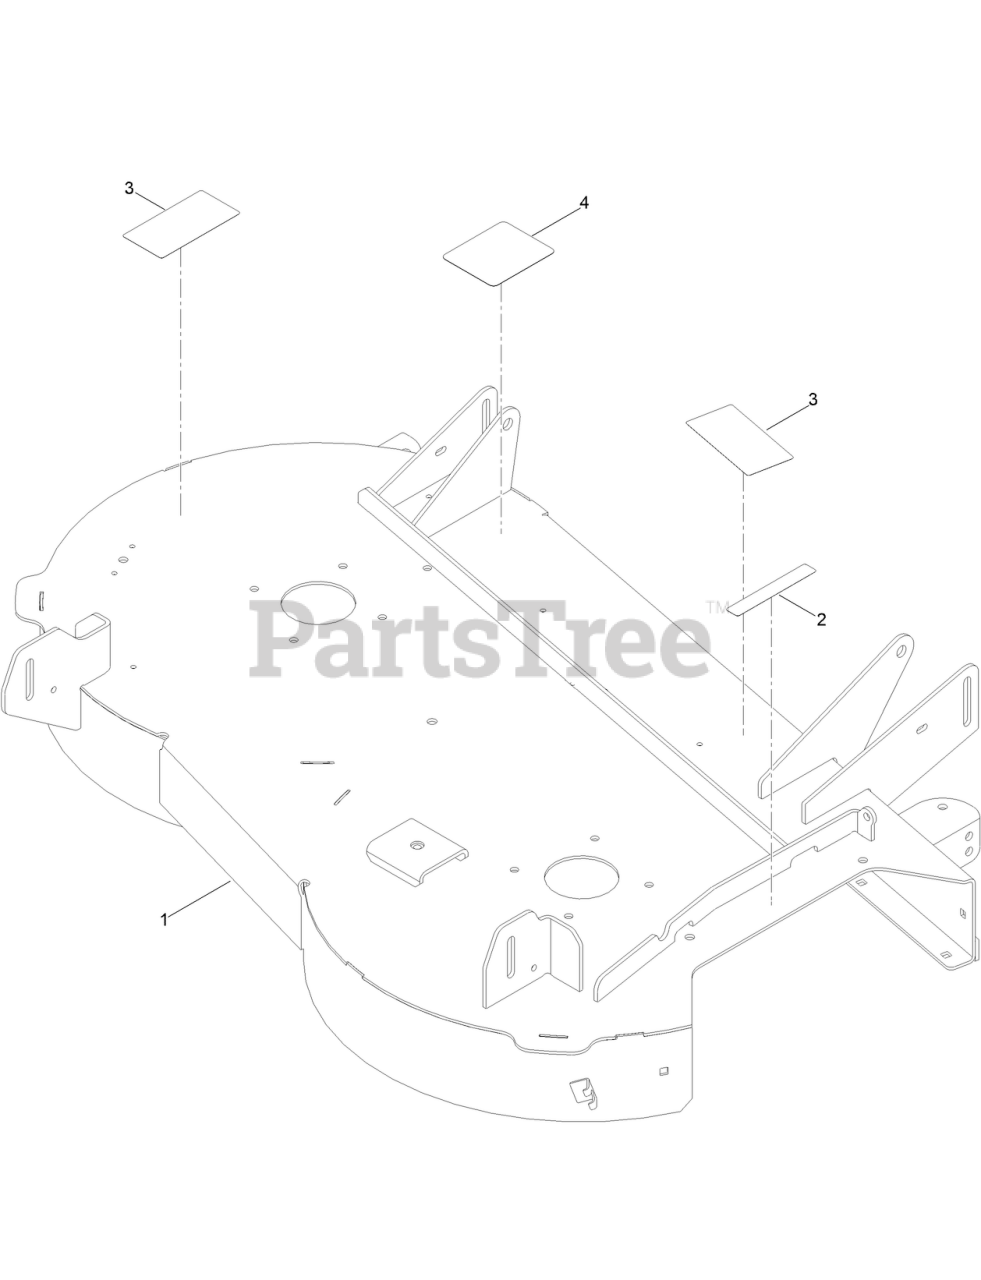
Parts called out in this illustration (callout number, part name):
2	DECAL-DANGER
3	DECAL-DANGER, DECK
4	DECAL-BELT ROUTING 42IN
